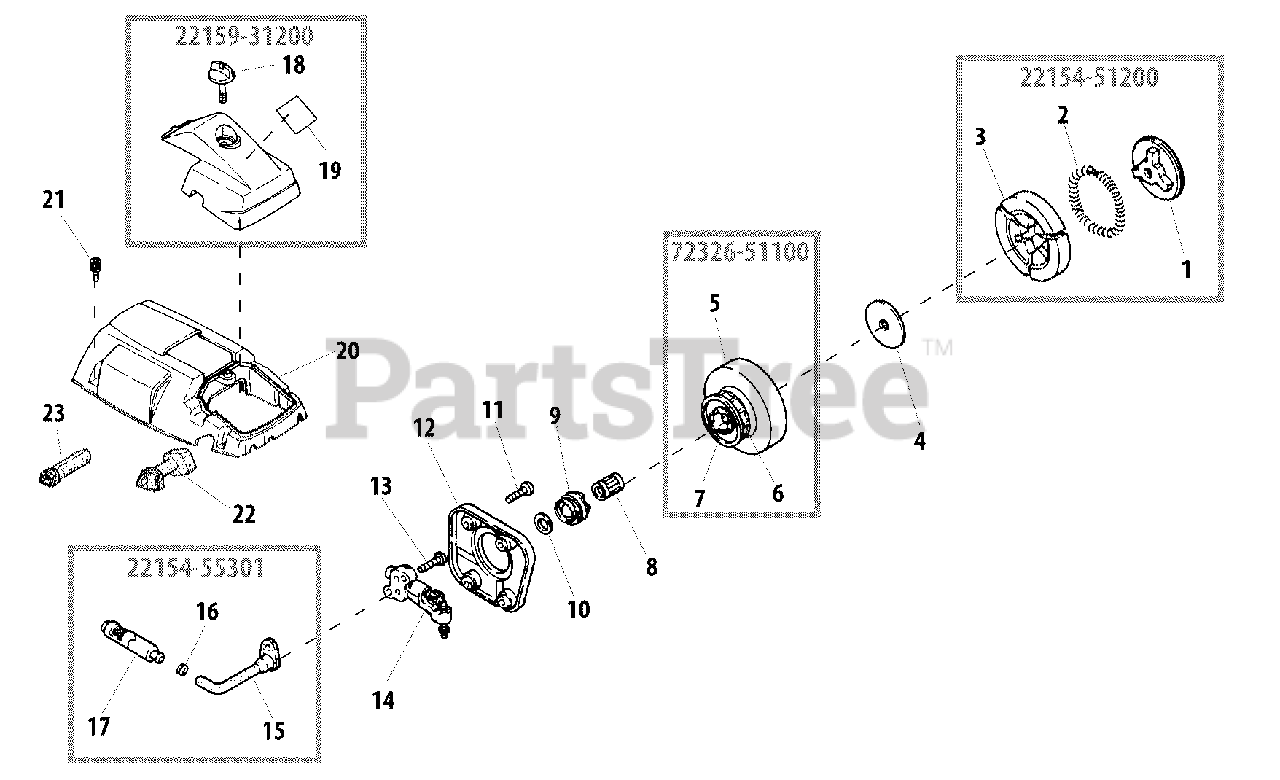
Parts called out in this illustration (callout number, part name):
1	BOSS, CLUTCH
2	SPRING, CLUTCH
3	SHOE, CLUTCH
4	WASHER, CLUTCH
5	DRUM, CLUTCH
6	SPROCKET, 0.325 RIM
7	COVER
8	BEARING, NEEDLE
9	GEAR
10	PLATE, THRUST
11	SCREW, ADHESIVE M4×12
12	COVER, PUMP
13	SCREW, ADHESIVE M4×12
14	OIL PUMP ASSY
15	PIPE, OIL
16	CLIP
17	FILTER, OIL
18	THUMBSCREW
19	LABEL, CAUTION K
20	COVER, ENGINE
21	BOLT, ADHESIVE M4×16
22	GROMMET
23	GROMMET
22154-51200	CLUTCH ASSY
22154-55301	PIPE ASSY, OIL
22159-31200	AIR FILTER COVER ASSY
72326-51100	DRUM ASSY, CLUTCH
